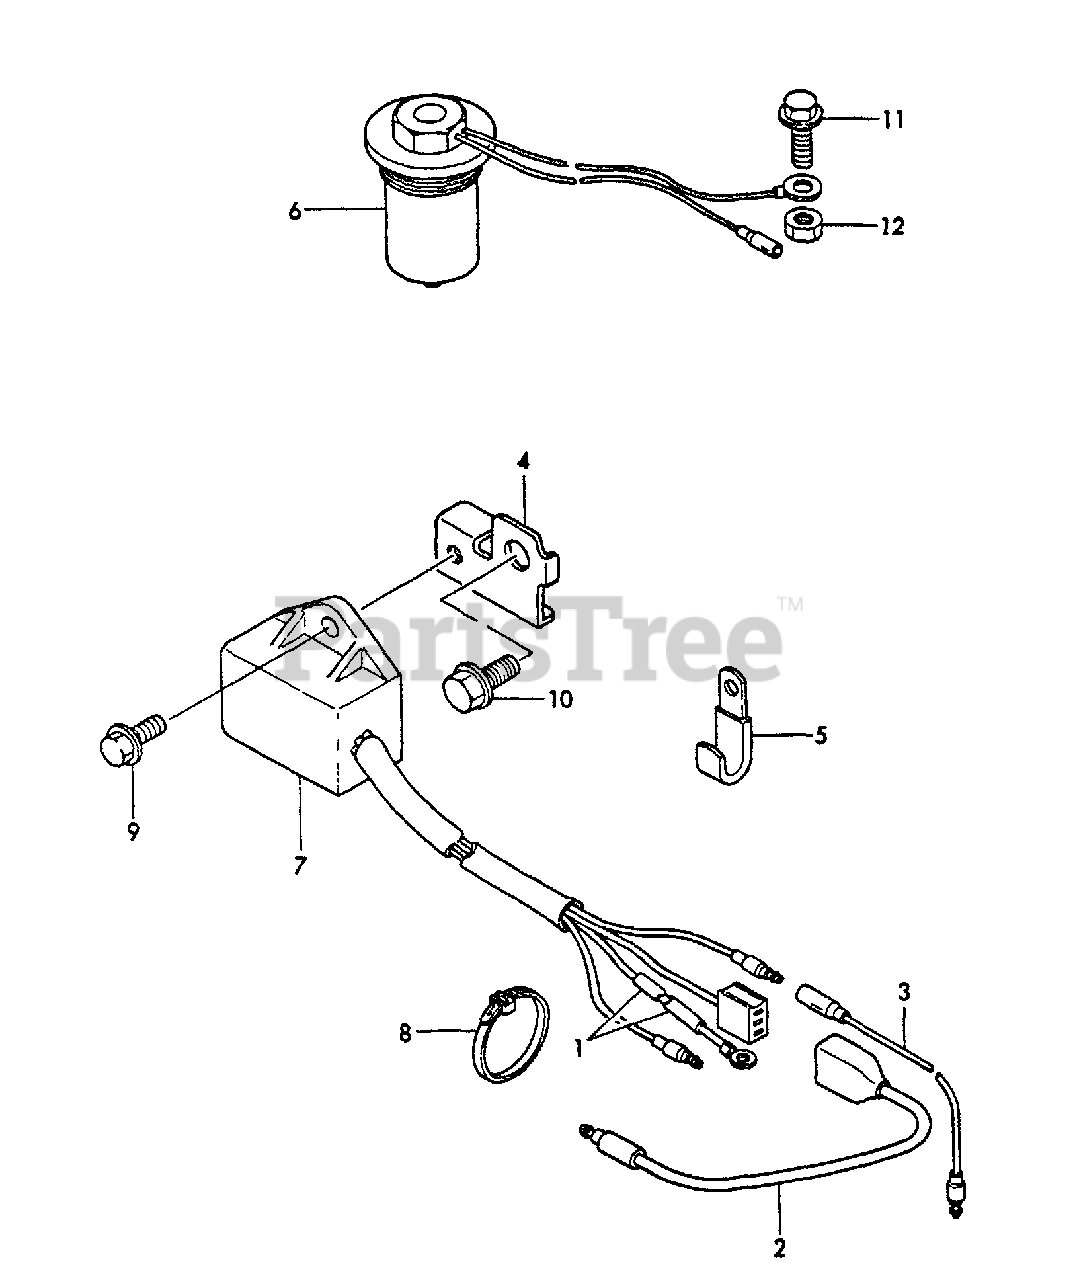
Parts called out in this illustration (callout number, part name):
1	TUBE, INSULATOR
2	WIRE
3	WIRE, SENSOR UNIT
4	STAY, SENSOR UNIT
5	CLAMP
6	SENSOR, OIL LEVEL
7	SENSOR, OIL
8	CLAMP
9	BOLT - 6X12 -- PLATED
10	BOLT - 8X14 -- PLATED
11	BOLT - 6X16 -- PLATED
12	LOCKNUT - 6 -- PLATED
